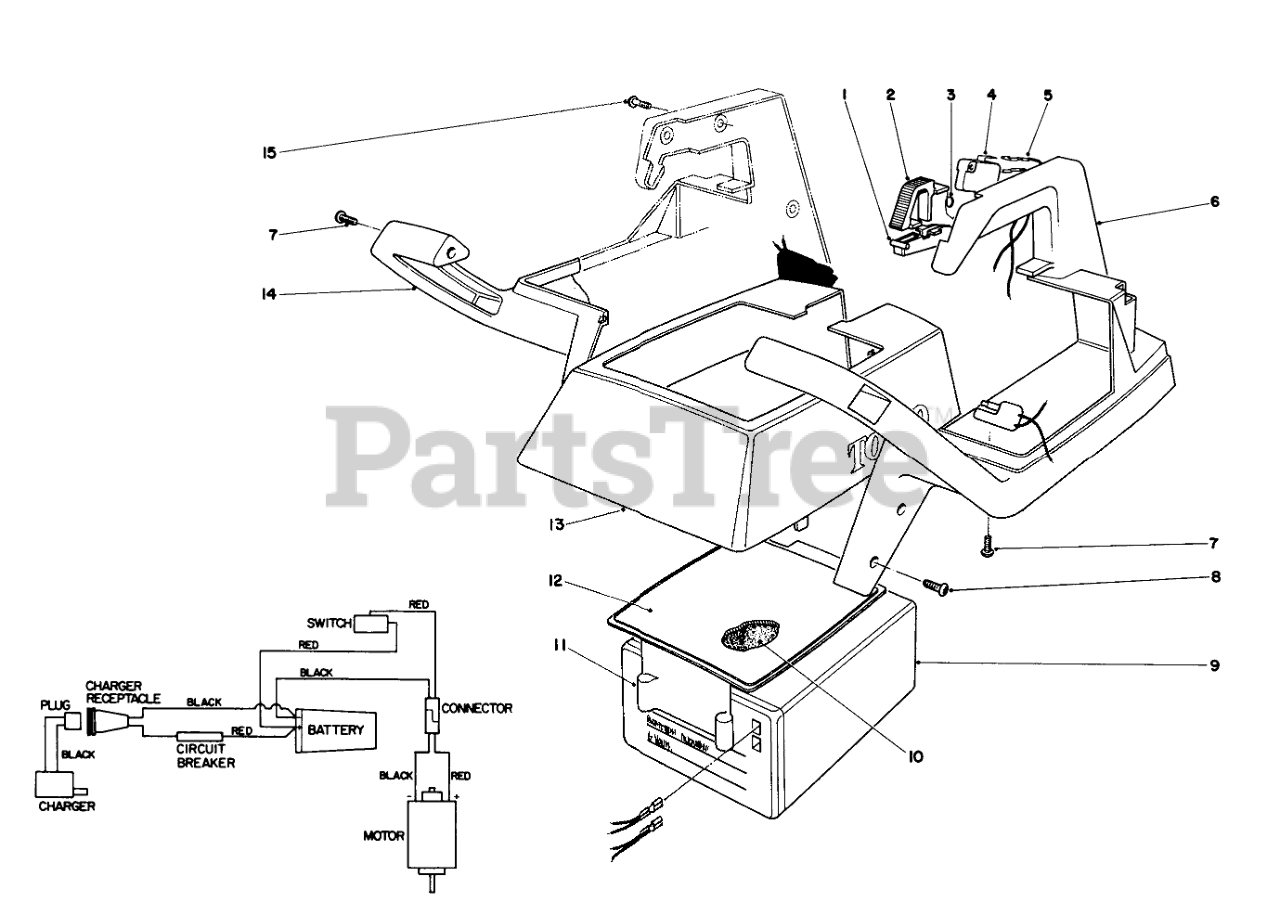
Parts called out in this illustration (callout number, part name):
1	TRIGGER
2	TRIGGER LOCK
3	SPRING
4	Switch
5	Wiring Harness
6	LH BATTERY CASE/HNDL
7	Screw
8	10-16 X .31 SCREW
9	BATTERY
10	FOAM PAD
11	CONTROL PANEL, CL-710
12	DECAL CL 710 PANEL
13	COVER,CL710,HOTSTAMPED
14	RH BATTERY CASE/HNDL
15	SCREW-PPH
